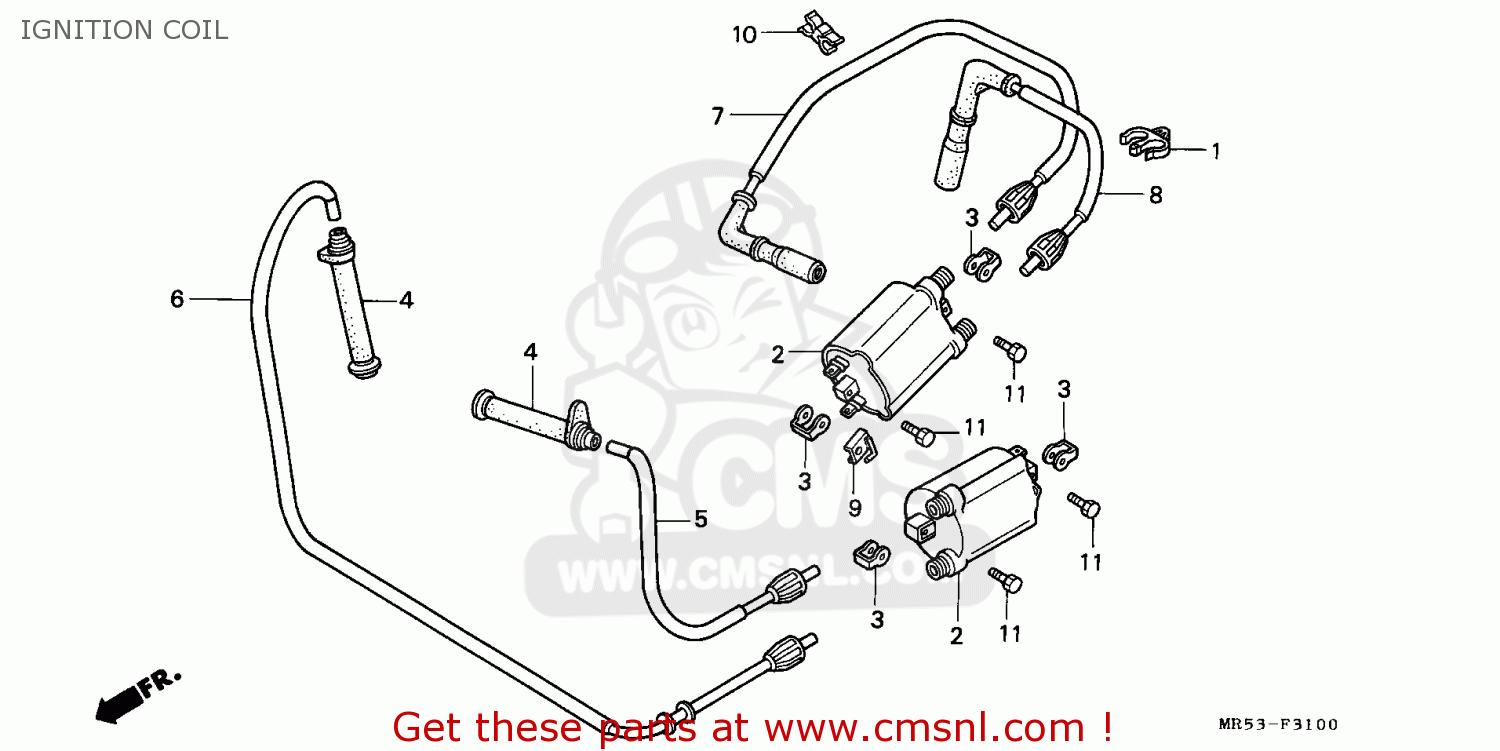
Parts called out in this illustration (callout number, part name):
1	CLAMP,AUTO CHOKE
2	COIL COMP.,IGNITI
3	SPACER,IGNITION C
4	CAP ASSY.,NOISE (
5	CAP ASSY.HIGH/T 1
6	CORD HIGH/T 2
7	CAP ASSY.,HIGH/T
8	CAP ASSY.,HIGH/T
9	GUARD
10	CLIP,WIRE
11	BOLT,HEX.,6X20
